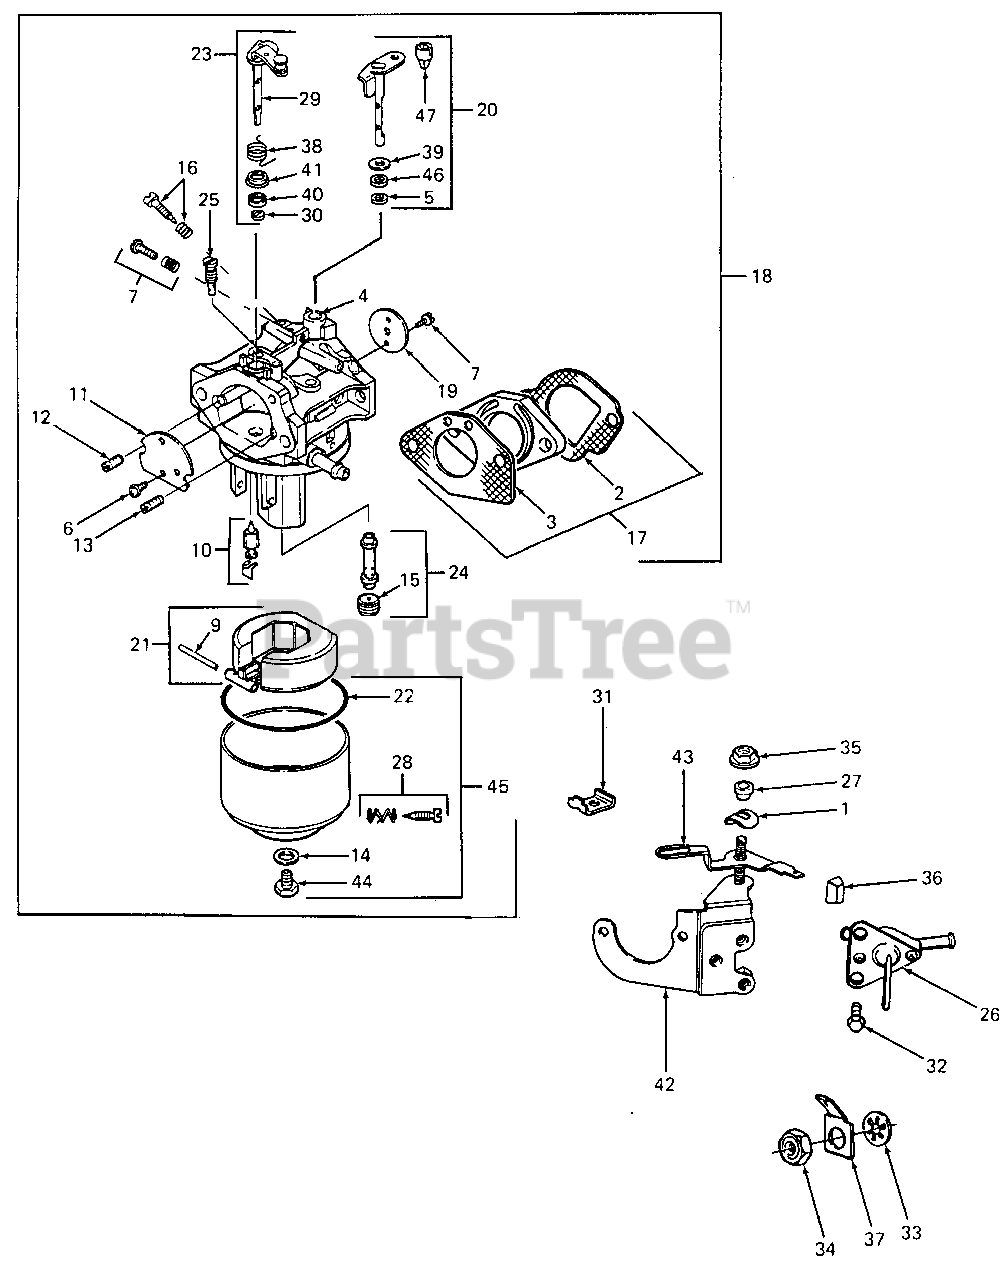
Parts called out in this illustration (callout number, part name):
1	Washer, Spring
2	Gasket, Adapter
3	Gasket, Adapter
4	Bushing, Throttle Shaft (Upper)
5	Bushing, Throttle Shaft (Lower)
6	Screw, Mtg
7	Screw, Mtg
9	Pin, Float Hinge
10	Valve, Float
11	Valve, Choke
12	Nozzle, Carburetor
13	Nozzle, Carburetor
14	Gasket, Sealing
15	Jet, Main
16	Valve Assy, Carburetor
17	Spacer, Carburetor
18	Carburetor Assy
19	Valve, Throttle
20	Shaft, Throttle
21	Float Assy, Carburetor
22	Gasket, Bowl
23	Shaft Assy, Choke
26	Valve, Fuel Shut-Off
27	Bushing, Lever
28	Drain, Carburetor
29	Retainer, Choke Shaft (Upper)
30	Retainer, Choke Shaft (Lower)
31	Clamp, Casing
32	Screw, Sems
33	Lockwasher
34	Nut, Hex, 8-32
36	Knob, Air Cleaner
37	Terminal, Spade
38	Spring, Choke Shaft
39	Washer, Throttle Shaft
40	Washer, Choke Shaft
41	Washer, Choke Shaft Seal
42	Bracket & Nut Assy, Choke
43	Lever, Choke
44	Screw, Bowl Mtg
45	Bowl Assy, Carburetor
46	Seal, Throttle Shaft
47	Retainer, Link
